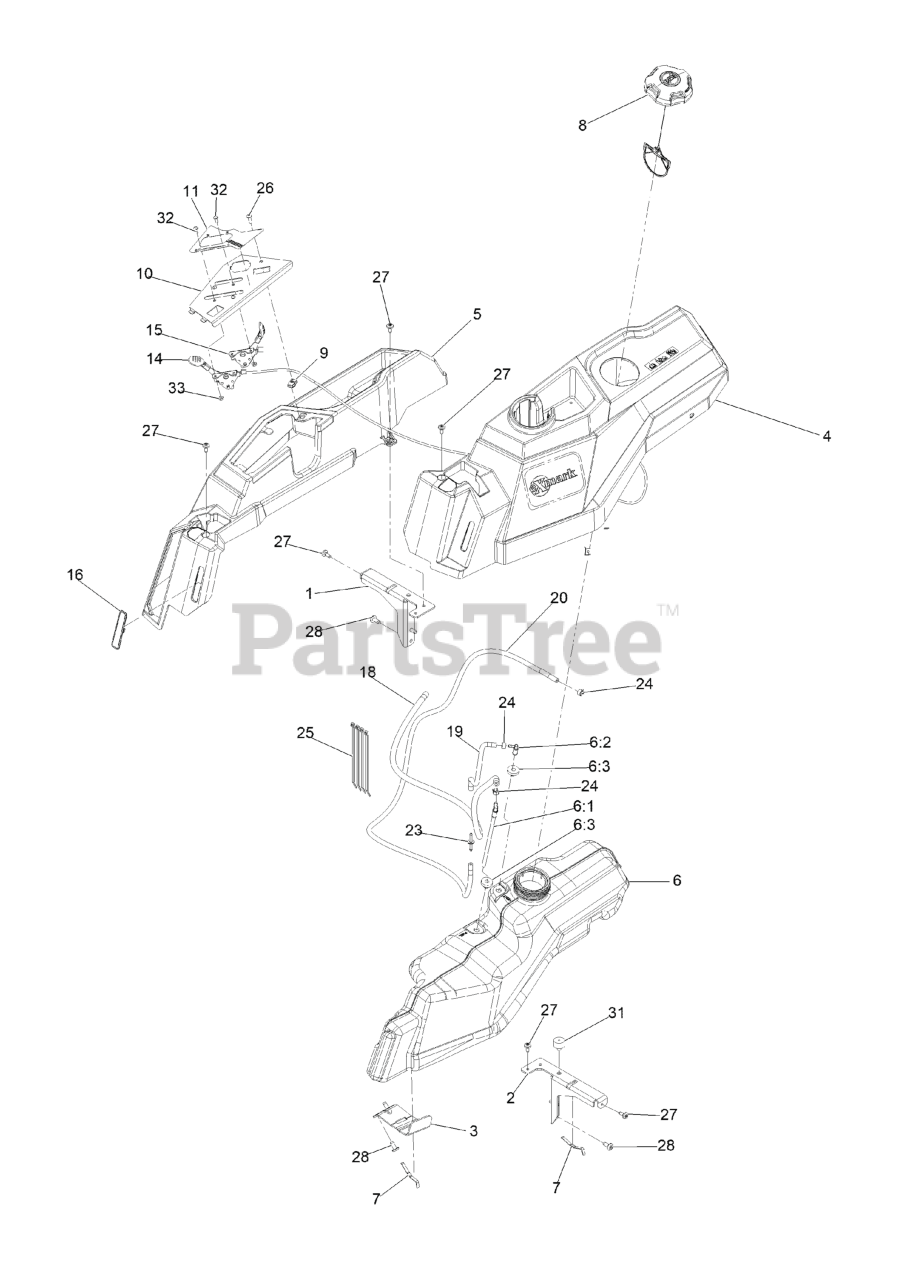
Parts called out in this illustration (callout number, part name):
1	SUPPORT-POD, RH
2	SUPPORT-POD, LH
3	SUPPORT-TANK, FUEL
4	POD- LH
5	POD- RH
6	FUEL TANK ASM
6:1	Connector-Elbow, 90 DEG
6:2	FITTING-PLASTIC
6:3	BUSHING
7	SPRING
8	CAP-FUEL, RATCHETING
10	PANEL- CONTROL
11	DECAL-CONTROL PANEL
14	ASM,THROTTLE CABLE
15	CABLE-CONTROL, CHOKE
16	PLUG-SC
18	HOSE-FUEL
19	HOSE-FUEL
20	Hose-Fuel (.188 X .406 X 40.00)
23	ADAPTOR-ORIFICE
24	CLAMP-HOSE
25	TIE-CABLE
26	SCREW-PRH
27	SCREW-SHOULDER
31	BUMPER-GROMMET
32	SCREW-PPH
33	NUT-LOCK, NI
